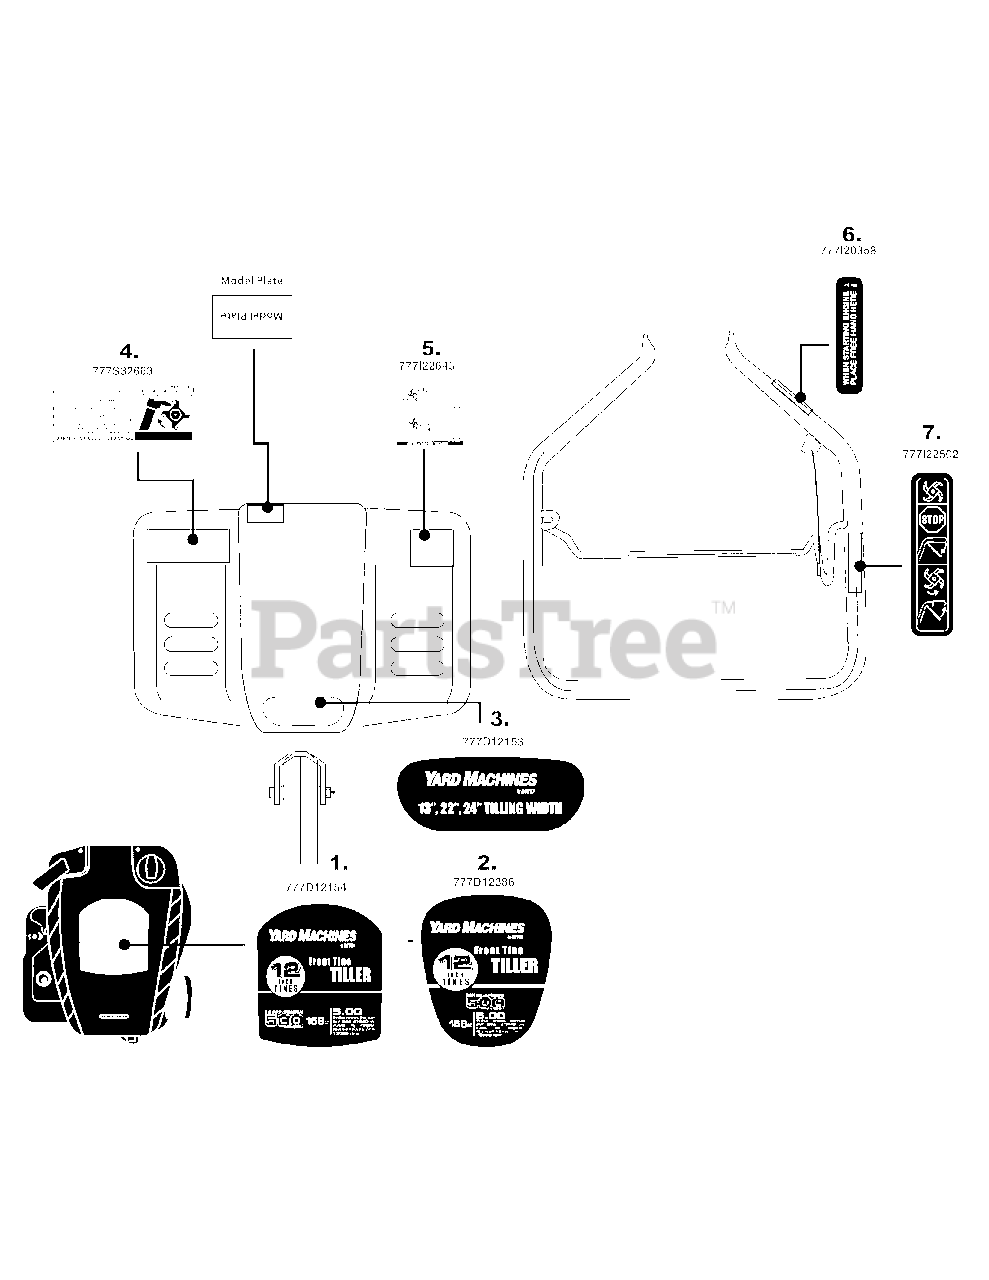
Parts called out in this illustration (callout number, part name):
1	LABEL-TILLER SHROUD YARD MACHINE
2	LABEL-TILLER SHROUD YARD MACH
3	LABEL-TILLER TINE SHIELD YARD MACH
4	LABEL-TILLER TINE SHIELD:WARNING
5	LABEL-TILLER FRNT/WHL DO NOT TILL
6	LABEL-PLACE HAND HERE
7	LABEL:TILLER HANDLE:ENGAGE
